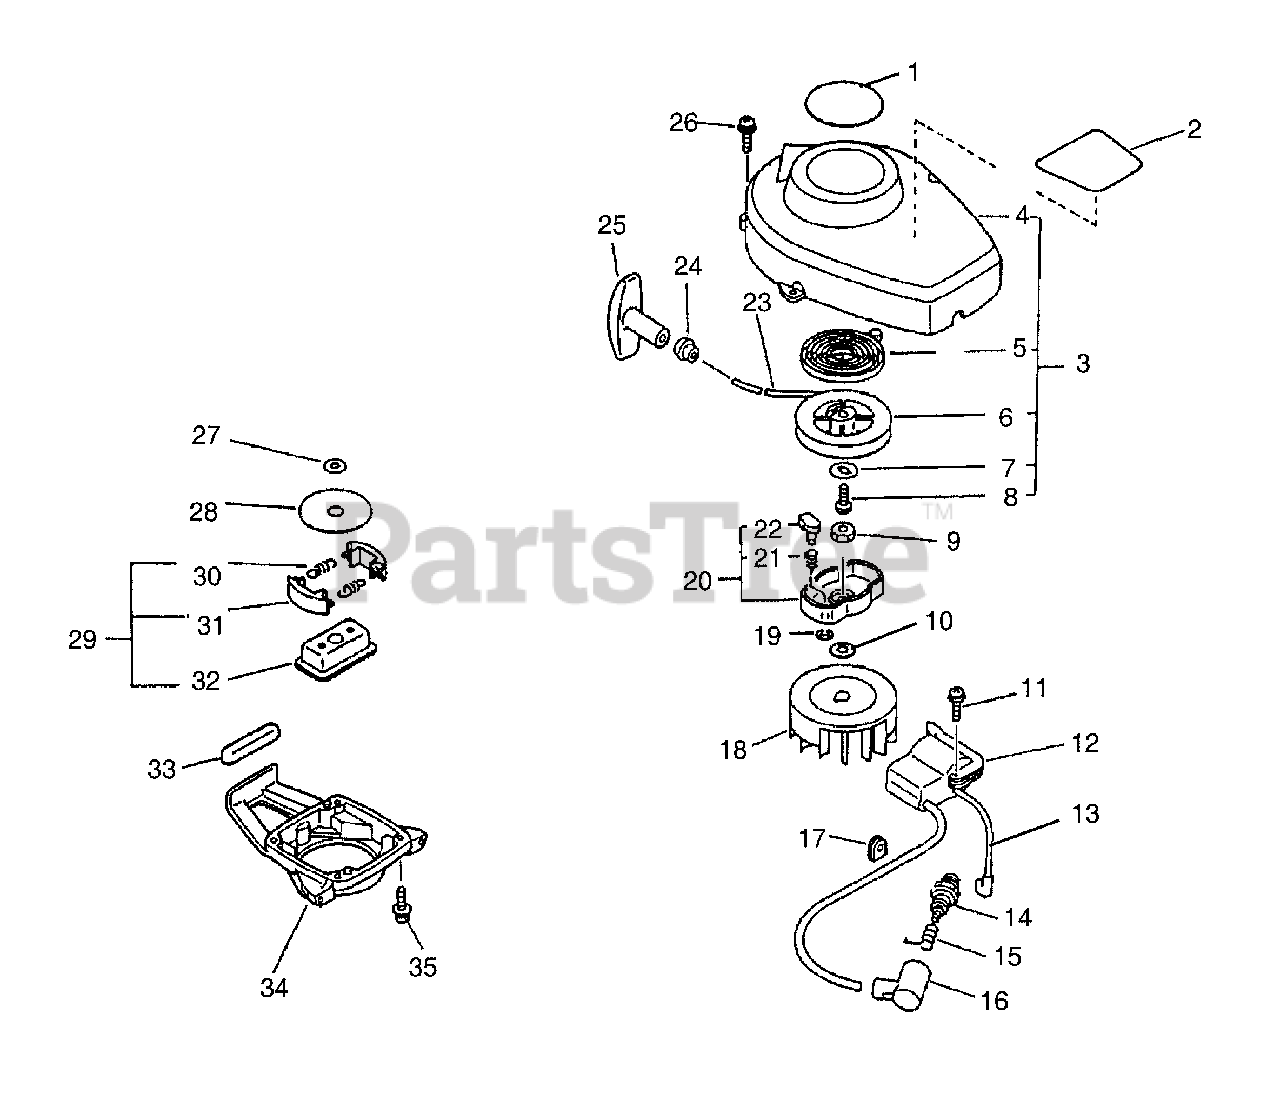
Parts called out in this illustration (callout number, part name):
1	LABEL - MODEL
2	LABEL - CAUTION
3	STARTER ASSY
4	CASE, STARTER
5	SPRING, REWIND
6	REEL, ROPE
7	WASHER
9	NUT - LEFT HAND
10	LOCKWASHER - 8
11	SCREW - 4X22
12	COIL, IGNITION
13	LEAD - IGNITION
14	SPARK PLUG -- BPM-7Y
14	SPARK PLUG -- BPMR-7A
15	TERMINAL, SPARK PLUG CAP
16	CAP, SPARK PLUG
18	FLYWHEEL
19	RING, RETAINING - 4
20	STARTER PAWL ASSY
21	SPRING, RETURN
22	PAWL, STARTER
23	ROPE, STARTER - 3.5X1000
24	GUIDE, ROPE
25	GRIP, STARTER
26	SCREW - 4X16
27	WASHER, CLUTCH
28	PLATE, CLUTCH
29	CLUTCH ASSY
30	SPRING, CLUTCH
31	SHOE, CLUTCH
32	HUB, CLUTCH
33	CUSHION, FUEL TANK
34	CASE, CLUTCH
35	SCREW - 4X16
